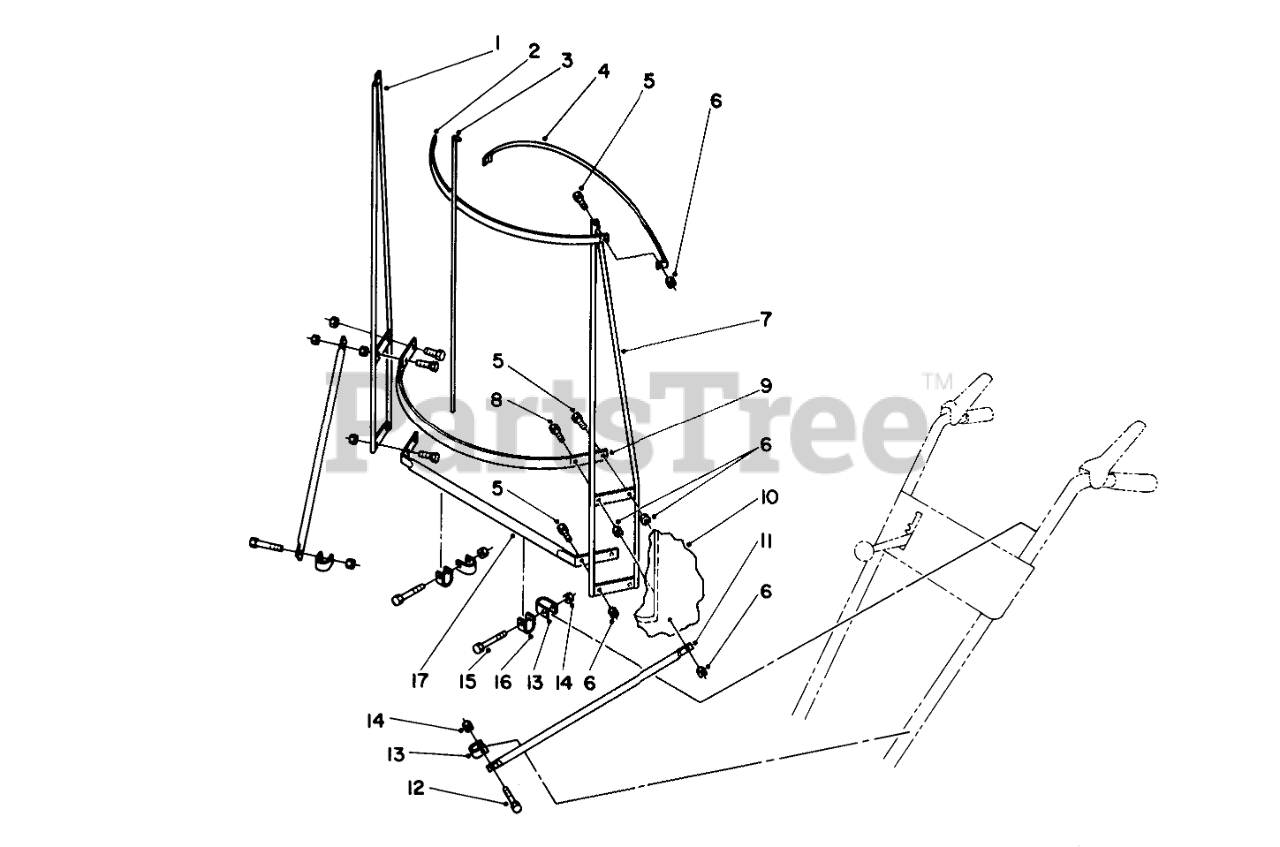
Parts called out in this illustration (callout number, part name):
1	RH SIDE FRAME
2	TOP BOW
3	CENTER SUPPORT
4	TOP FRAME
5	SCREW-HH
6	NUT-LOCK, NI
7	LH SIDE FRAME
8	SCREW-HH
9	BOTTOM BOW
10	VINYL COVER
11	BRACE
12	SCREW-HH
13	"U" CLAMP - .875
14	NUT-LOCK, NI
15	SCREW-HH
16	"U" CLAMP - .750
17	CROSS BAR
